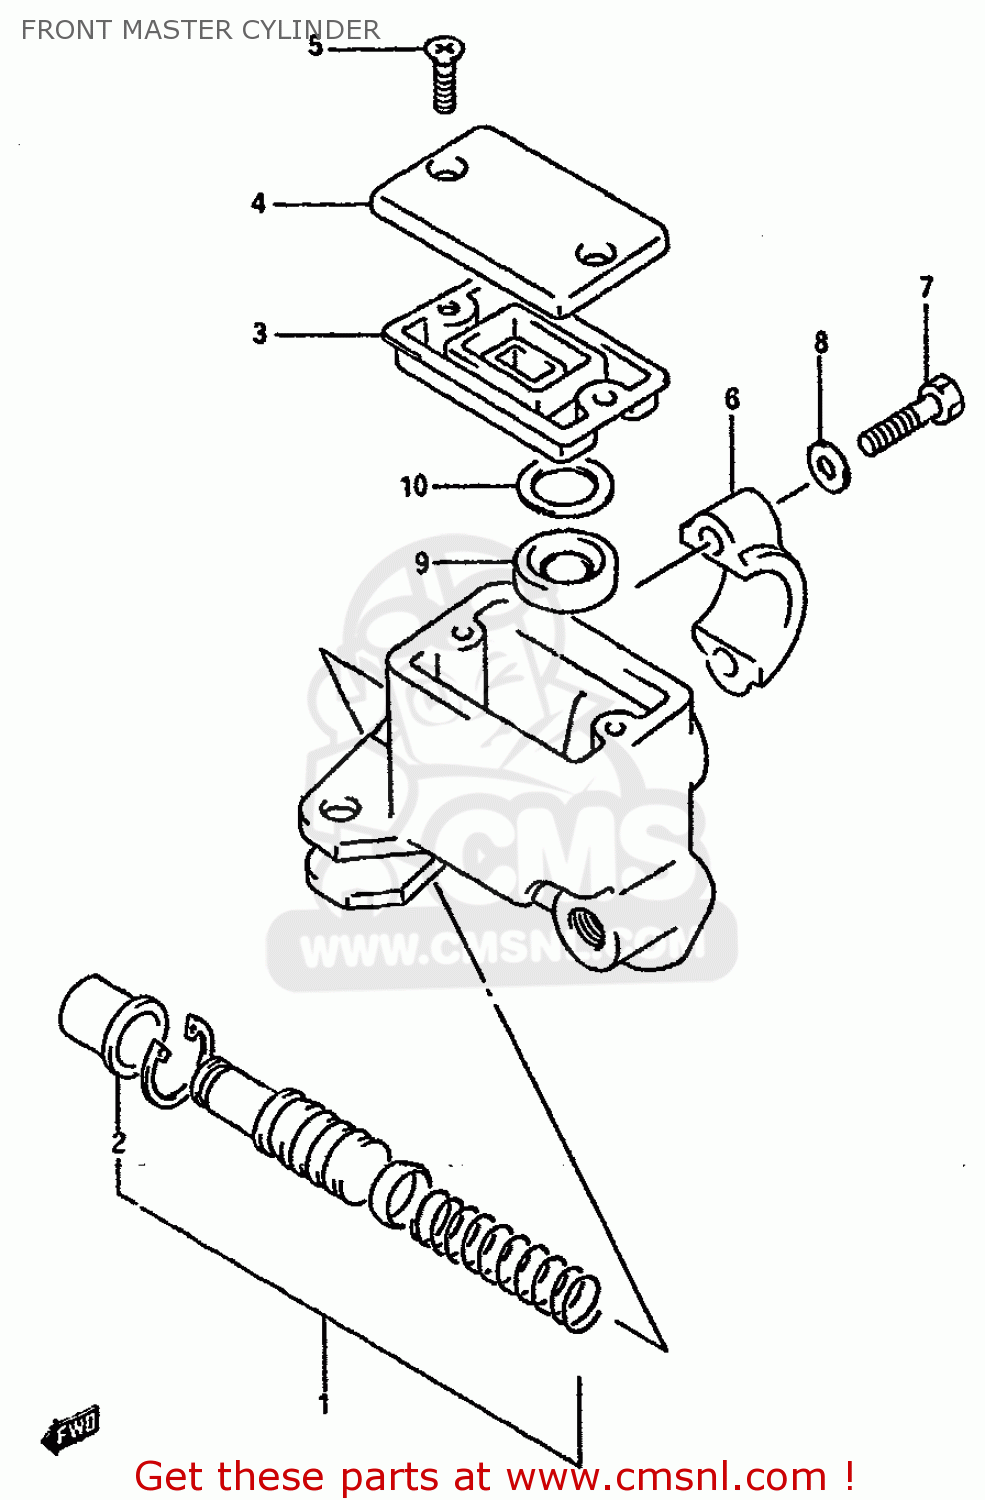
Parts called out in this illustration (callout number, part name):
1	PISTON & CUP SET
2	BOOT
3	DIAPHRAGM
4	CAP
5	SCREW
6	HOLDER
7	BOLT
8	WASHER
9	SEPERATOR
10	PLATE
